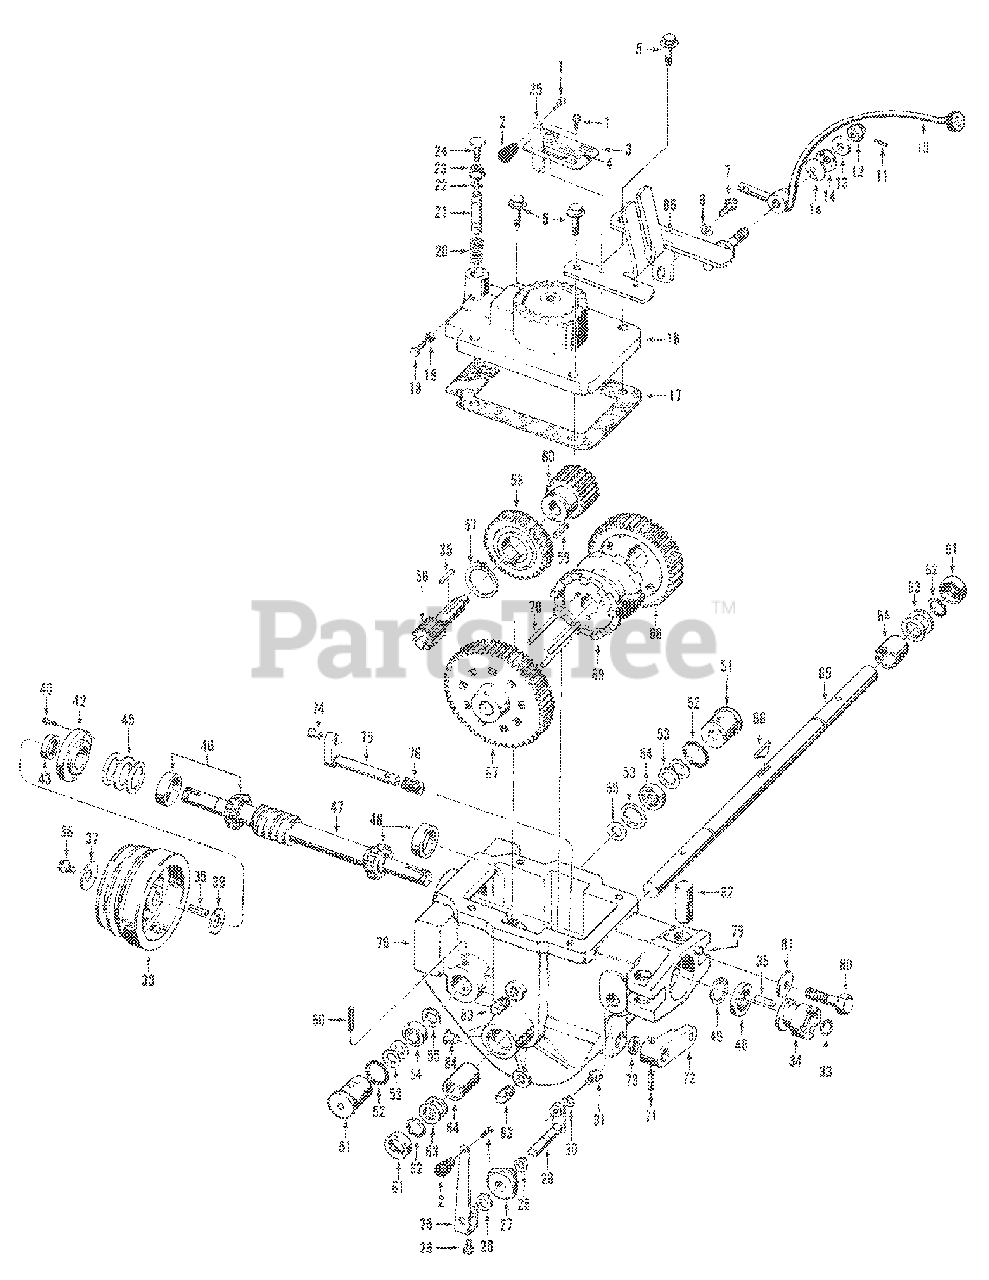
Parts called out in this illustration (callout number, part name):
1	Bolt-hex hd., #10-32 x 3/8", self-locking flange
2	Knob-tines/PTO clutch lever, tapered, plastic
3	Detent Plate-tines/PTO clutch lever
4	Decal-operating instructions, detent plate
5	Bolt-flanged hex hd., 3/8-16 x 1-1/2"
7	Bolt-flanged hex hd., 5/16-18 x 3/4", Grade 5
9	Washer-flat, 5/16", SAE.
11	Pin-spring, 1/8"
12	Nut-castle (Slotted) 1/2"-20
13	Washer-shoulder, 1/2"
14	Washer-disc spring
15	Lever-wheel speed shift
16	Cover-power unit transmission
17	Gasket-transmission cover
18	Bolt-hex hd., 5/16-18 x 1", Grade 5 (remove with care)
19	Nut-hex, 5/16"-18
20	Spring-neutral plunger (remove with care)
21	Plunger-neutral (remove with care)
22	Clip Ring-retains neutral plunger
23	Nut-hex, flange locknut, 3/8"-16
24	Bolt-hex hd., 3/8-16x1-1/2", threaded full length
25	Lever-eccentric, tines/PTO clutch
26	Bolt-hex hd., 1/4-20 x 1/2"
27	Bushing-tines/PTO clutch lever eccentric shaft
28	Retaining Ring-(snap ring) external
29	Eccentric-shaft, tines/PTO clutch lever
30	Lockwasher-hi-collar, 1/4"
31	Screw-socket hd., 1/4-20 x 3/8"
33	Retaining Ring-external
34	Dog Clutch-power unit
35	Key-3/16 sq x 1"
36	Bolt-hex hd., 5/16-24 x 3/4", self-locking flange, Grade 5
37	Washer-disc spring (concave)
38	Pulley-transmission drive, cast iron
39	Washer-flat, hardened shoulder 1-1/4
40	Bolt-hex hd., 1/4-20 x 3/4 front bearing cap
42	Cap-front bearing
43	Seal-oil, front bearing cap
45	Shim-front bearing cap, 010" thick
45	Shim-as above, 030"
45	Shim-as above, 005"
45	Shim-as above, 062"
46	Bearing & Race
47	Shaft-main drive, power unit
48	Seal-oil, drive shaft, rear
49	Retaining Ring-(snap ring), internal
50	Pin-roll (spirol), 1/4 x 2"
51	Plug-retaining, pinion bearing
52	O-Ring-retaining plug
53	Shim-retaining plug, 1-1/64" inner diamter, .033" thick
53	Shim-same as GW-1132-1, .062"
53	Shim-same as GW-1132-1, .010"
54	Bearing-ball, pinion shaft
55	Washer-pinion shaft
56	Stem Pinion-slow speed gear & shaft
57	Ring-retaining, external
58	Worm Gear-bronze, wheel drive
59	Key-3/16" x 5/8"
60	Gear-fast speed pinion
61	Seal-oil, wheel shaft
62	Retaining ring-external
63	Shim-wheel shaft, 1-1/64" inner dia., .062" thick
63	Shim-as above, .030"
63	Shim-as above, .015"
63	Shim-as above, .010"
63	Shim-same as above, .005" thick
64	Bushing-bronze, wheel shaft bearing
65	Shaft-wheel, 15-5/8" w/key
66	Key-Hi Pro, 1/4" x 1-3/4"
67	Gear-slow speed, wheel drive
68	Gear-fast speed, wheel drive
69	Dog Clutch-wheel drive
70	Pin-clutch guide, 1/4" diameter
71	Pin-roll, 3/16" x 1-1/4" (spirol)
73	Seal-oil, eccentric shaft
74	Pin-eccentric shaft, shifting
75	Eccentric Shaft-wheel speed shifting
76	Spring-eccentric shaft
78	Housing-power unit transmission
79	Pin-alignment
80	Bolt-hex hd., 1/2-13 x .2"2 Grade 5
81	Washer-disc spring (concave), domed side faces bolt head
82	Post-with threaded hole for Ref. No. 80
83	Plug-pipe, 1/4"
84	Plug-red plastic, thread protector
86	Decal-forward interlock wire harness
